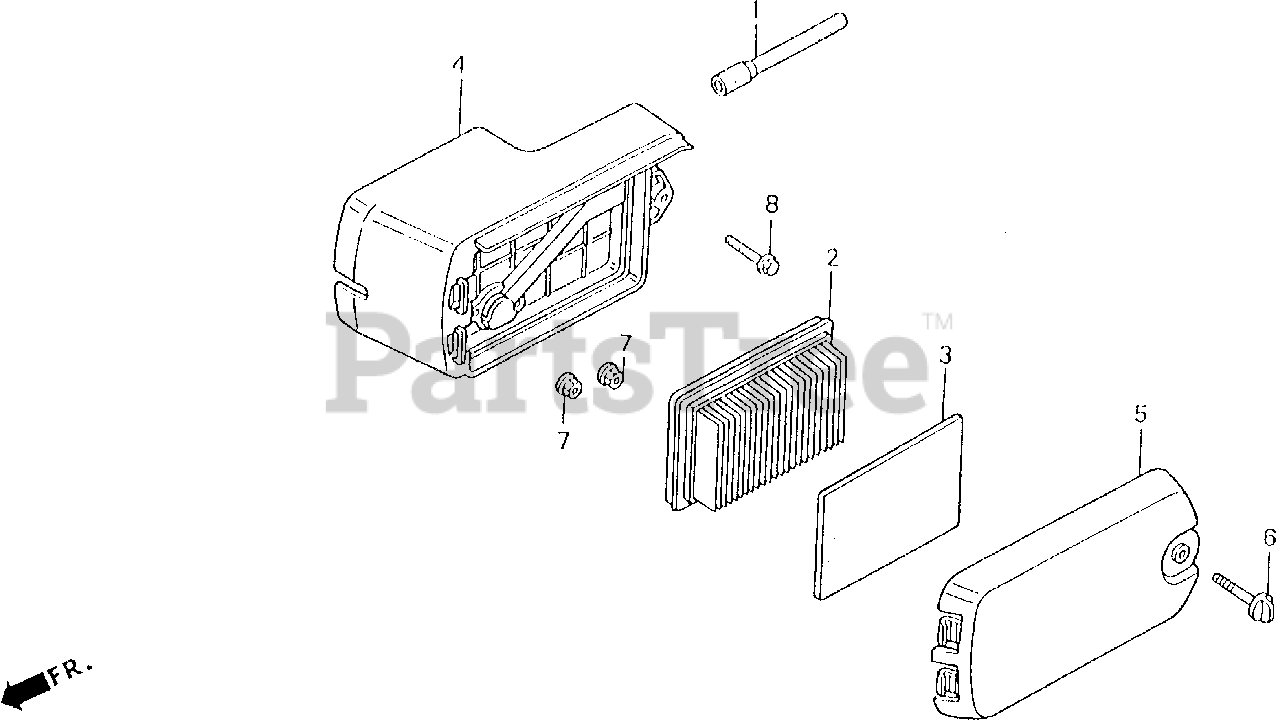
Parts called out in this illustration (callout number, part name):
1	TUBE, BREATHER
2	ELEMENT, AIR CLEANER
3	FILTER (OUTER)
4	HOUSING, AIR CLEANER
5	COVER, AIR CLEANER
6	BOLT, AIR CLEANER (6MM)
7	NUT, FLANGE (6MM)
8	BOLT, FLANGE (6X32)
